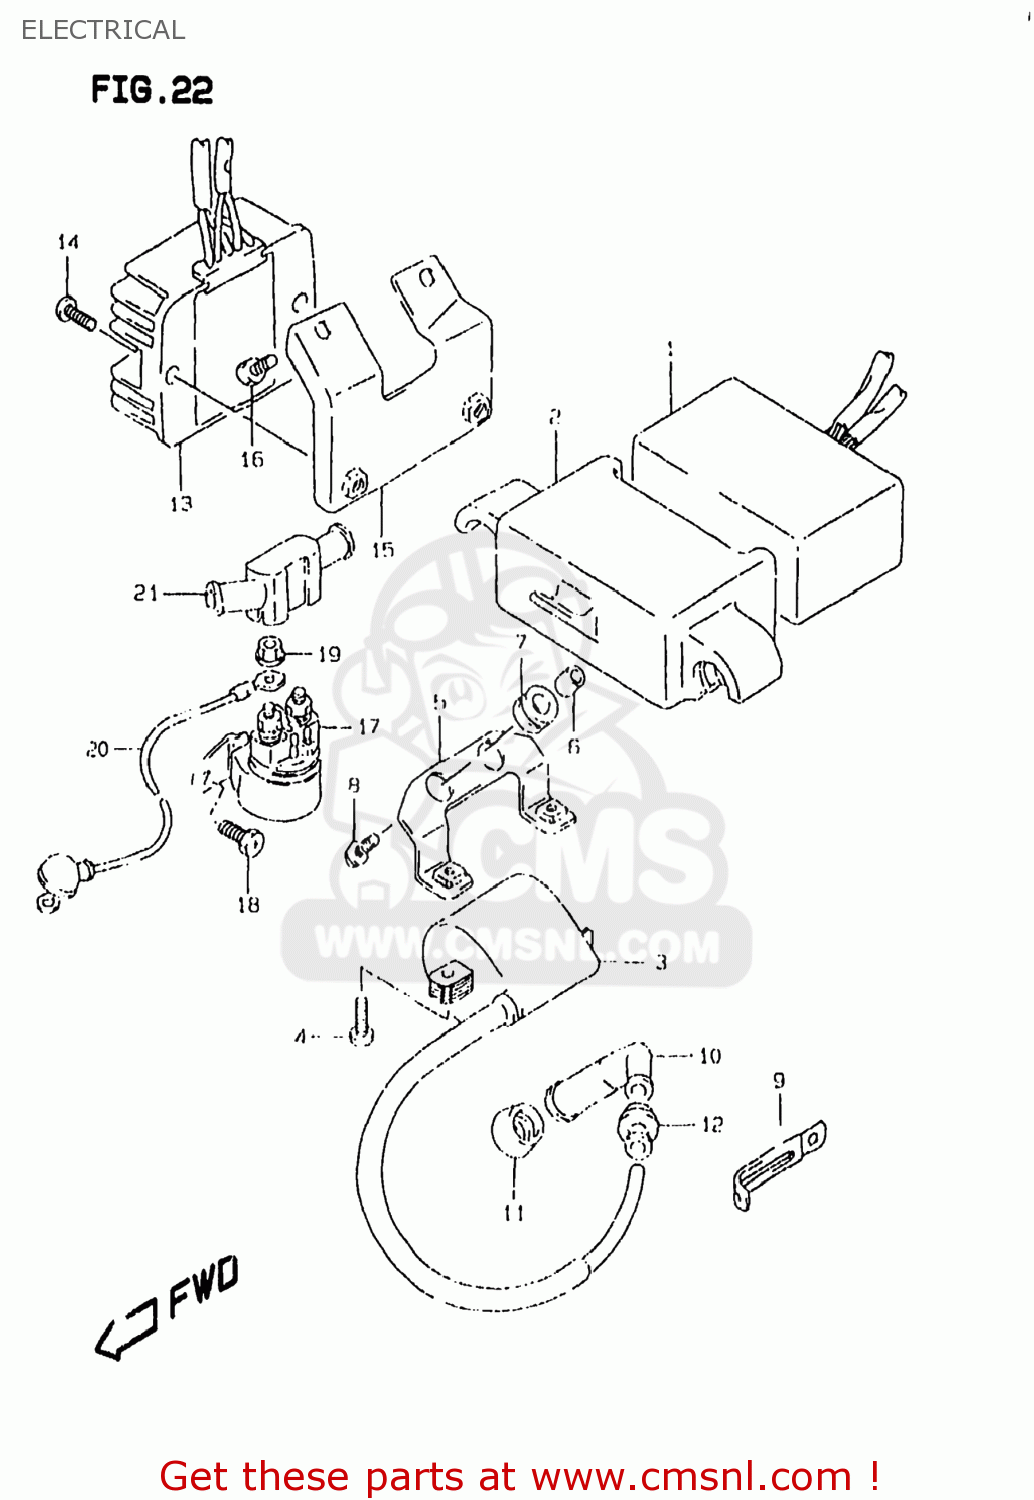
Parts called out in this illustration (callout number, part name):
1	CDI UNIT
2	CUSHION,CDI UNIT
3	COIL ASSY,IGNITION
4	SCREW, 6X20
5	BRACKET,IGNITION COIL
6	SPACER(6.5X9X6.7)
7	CUSHION
8	BOLT
9	CLAMP(L:45)
10	CAP,SPARK PLUG
11	SEAL,SPARK PLUG
12	SEAL,HIGH TENSION CORD
13	RECTIFIER ASSY
14	SCREW 6X16
15	BRACKET,RECTIFIER
16	BOLT
17	RELAY ASSY,STARTING MOTOR
18	SCREW(6X10)
19	NUT
20	WIRE,STARTER MOTOR LEAD
21	CAP,STARTER RELAY TERMINAL
